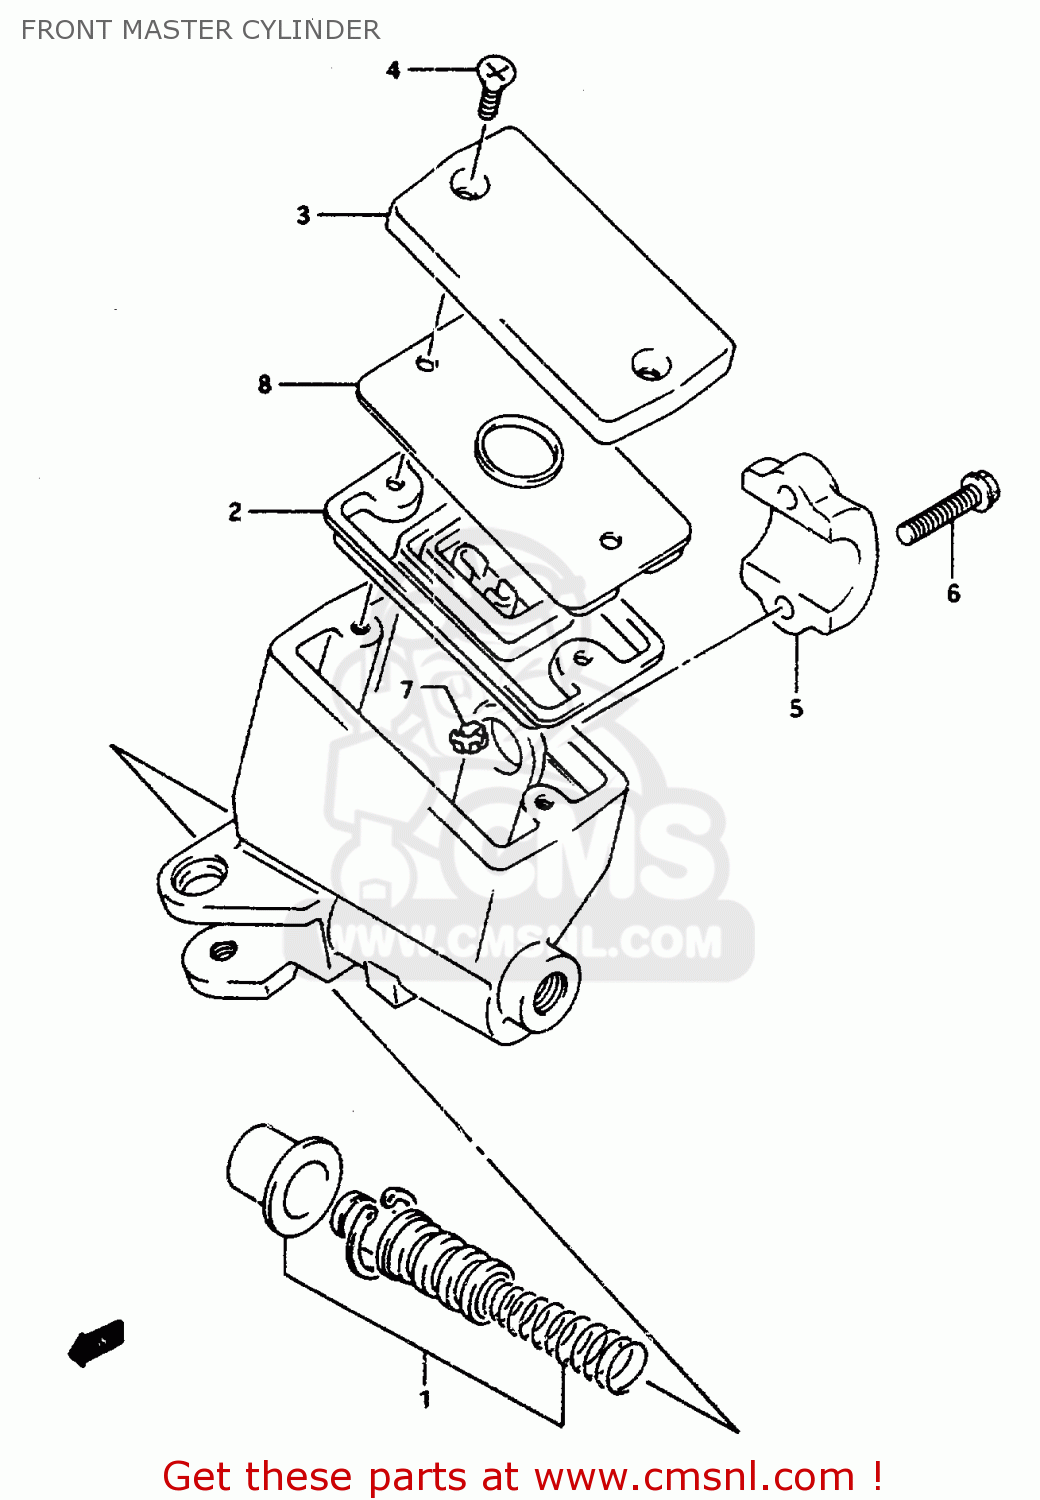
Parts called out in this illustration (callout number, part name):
00000	CYLINDER ASSEMBLY,FRONT MASTER
1	PISTON/CUP SET
2	3
3	CAP
4	SCREW
5	HOLDER
6	BOLT(6X25)
7	PROTECTOR
8	PLATE,DIAPHRAGM
